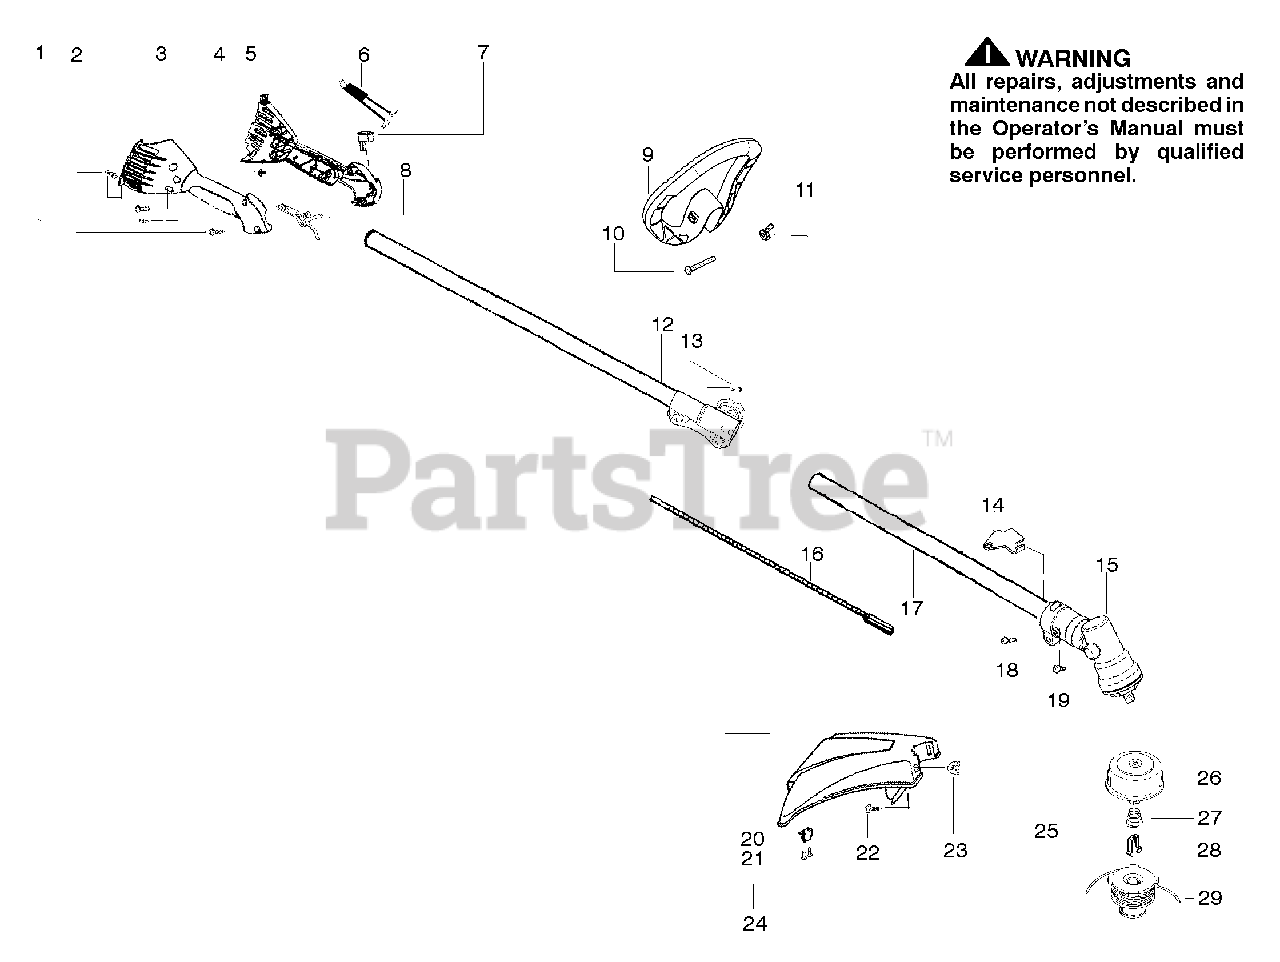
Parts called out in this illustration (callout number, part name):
1	Screw-alignment
3	Hsg.-Throttle-right
4	Screw-Cable Ret.
5	Hsg.-Throttle-left
6	Assy-Wire
7	Kit-Switch
8	Trigger-Throttle
9	Assy-Handle
10	Bolt-Handle
11	Wingnut
12	Kit-Upper Shaft
14	Bracket-Shield
16	Shaft-Flex (lower)
17	Kit-Lower Shaft Assy.
20	Limiter-Line
23	Wingnut
24	Kit-Shield Assy.
25	Accy-Cutting Head
26	Assy-Hub/Arbor
27	Spring-Return
28	Retainer-Spool
29	Accy-Wound Spool
